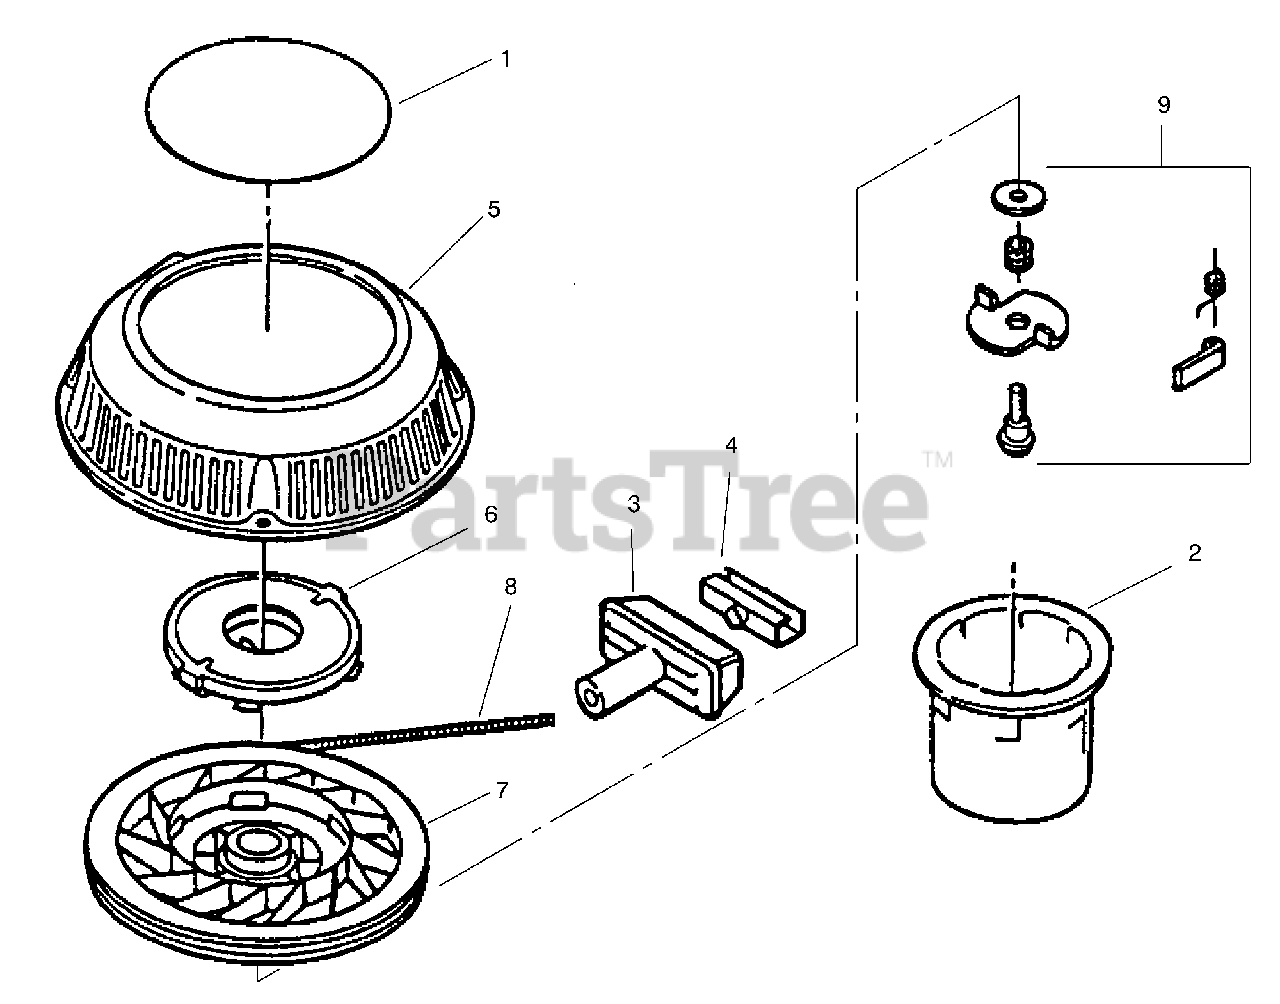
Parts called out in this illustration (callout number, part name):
2	Hub-Starter
3	Handle-Starter
4	Insert-Clip, Rope
5	Housing-Starter
6	Recoil Spring & Keeper
8	Rope
9	Assembly-Dog Kit
